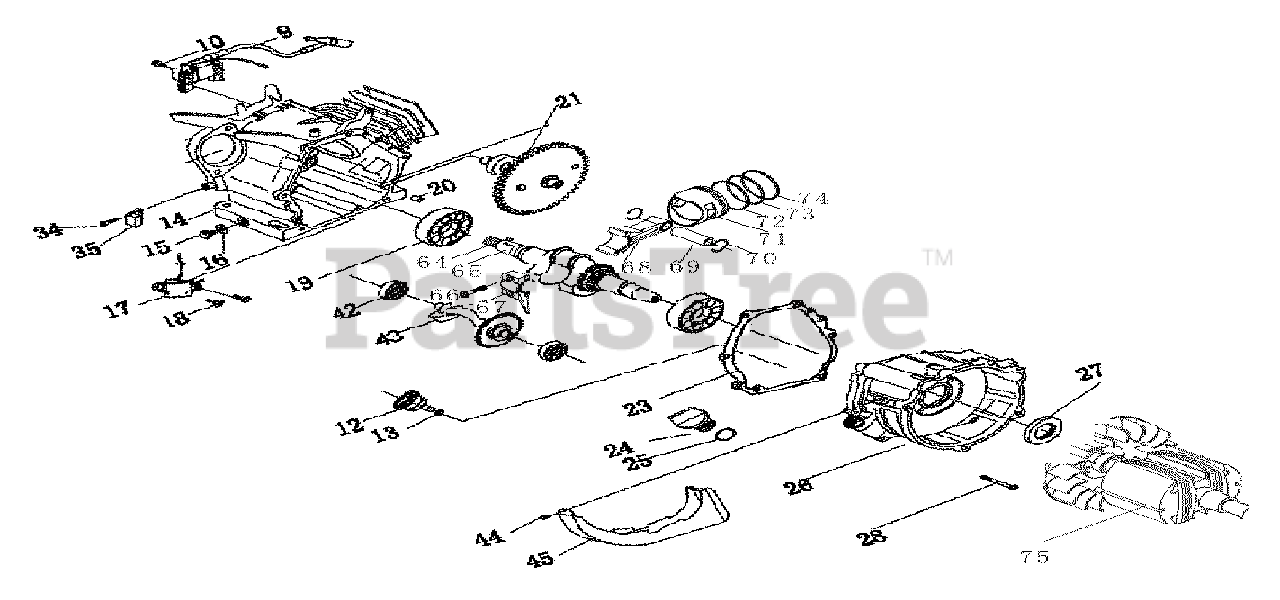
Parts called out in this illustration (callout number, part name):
9	IGNITION COIL
10	M6 x 25 bolt
12	Speed regulating wheel
14	Crankcase
15	Flanged bolt
17	Oil level gauge
18	M6 x12 flanged bolt
19	Bearing 6207
20	Locating ring
21	Camshaft
24	Oil cover
25	Ring seal
26	Crankcase cover
27	Oil seal
28	Flanged M8 x 35
34	M6 x 12 hexagon bolt
42	Cylinder head cover
43	Balancer shaft
44	M6 x 12 flanged bolt
45	Wind guide
64	Key 4 x 13
66	Flanged bolt
67	Connecting rod cap
68	Connecting rod
69	Piston pin
70	Piston pin circlip
72	Oil ring
73	2ndcompression ring
74	1stcompression ring
